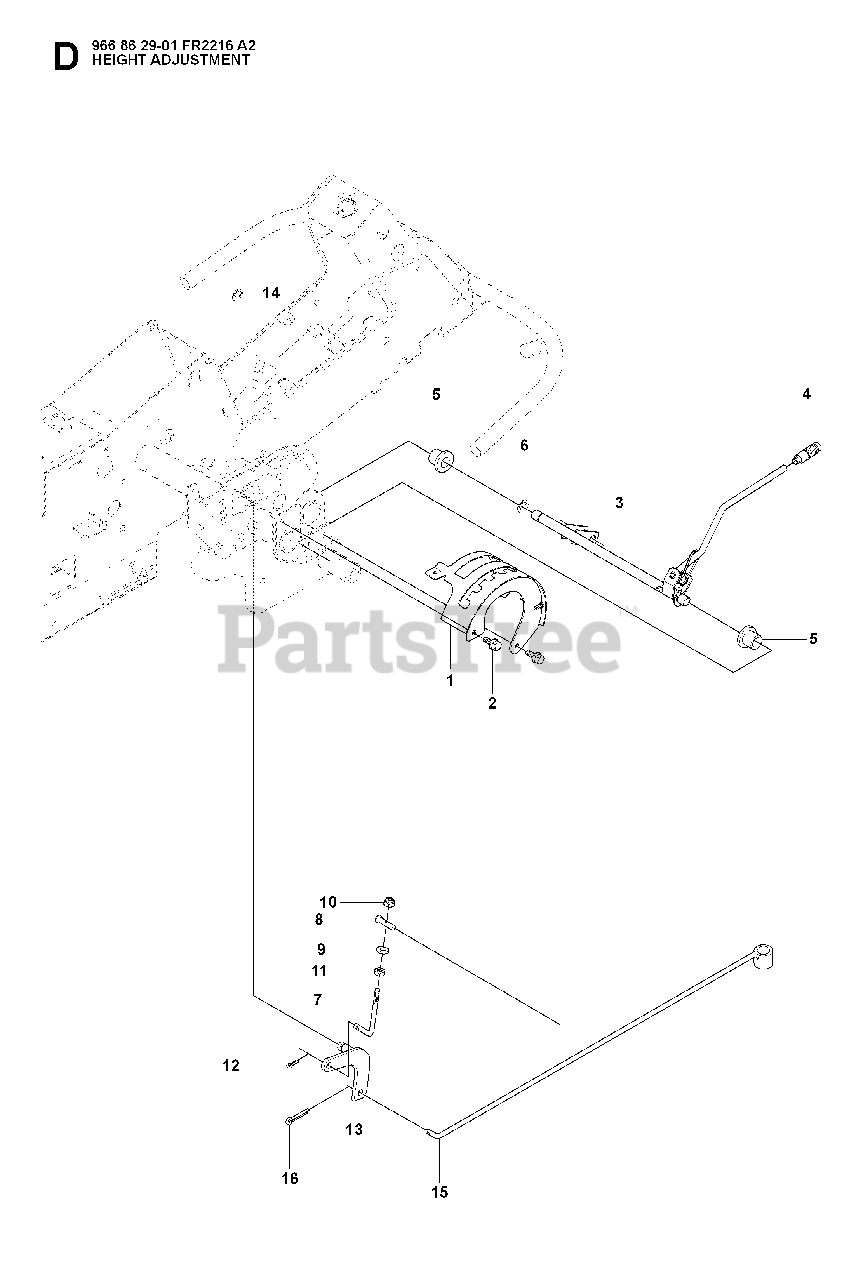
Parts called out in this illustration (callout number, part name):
4	GEAR STICK KNOB
5	BUSHING
9	WASHER
10	LOCKNUT M8
11	NUT
12	SPLIT PIN
14	RETAINING RING
15	CLUTCH ROD
16	SPLIT PIN
